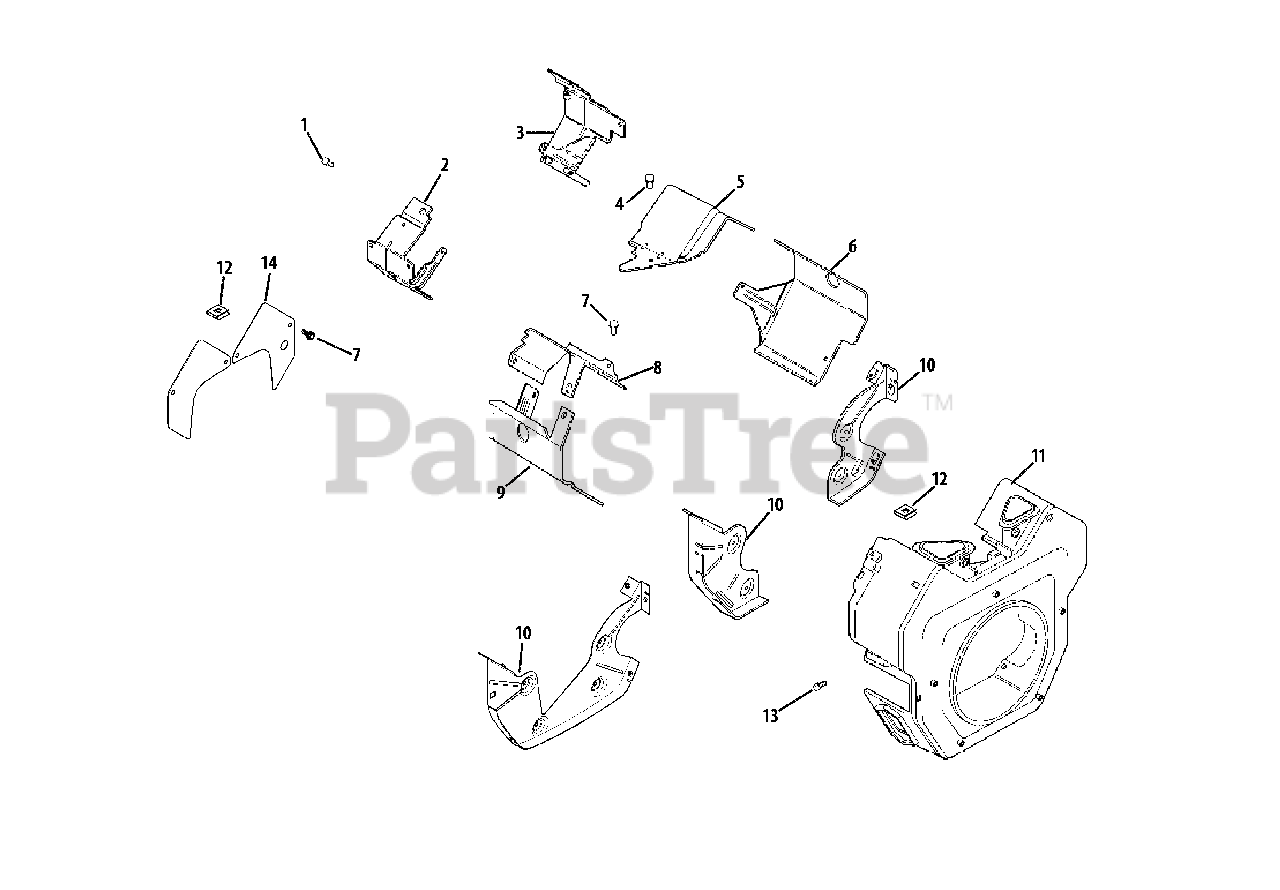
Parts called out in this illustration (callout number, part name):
1	Flange Screw, M6 x 1.0 x 10
2	Ducted Air-Oil Filter Baffle
3	Ducted Air-Starter Baffle
4	Thread Forming Screw
5	Valley Baffle, #1 Cylinder
6	Cylinder Baffle Kit, #1 Side
7	Thread Forming Screw
8	Valley Baffle, #2 Cylinder
9	Cylinder Baffle Kit, #2 Side
10	Backing Plate Kit
11	Blower Housing Assembly Kit
12	Baffle Mounting Clip
13	Thread Forming Screw
14	Access Panel Kit
